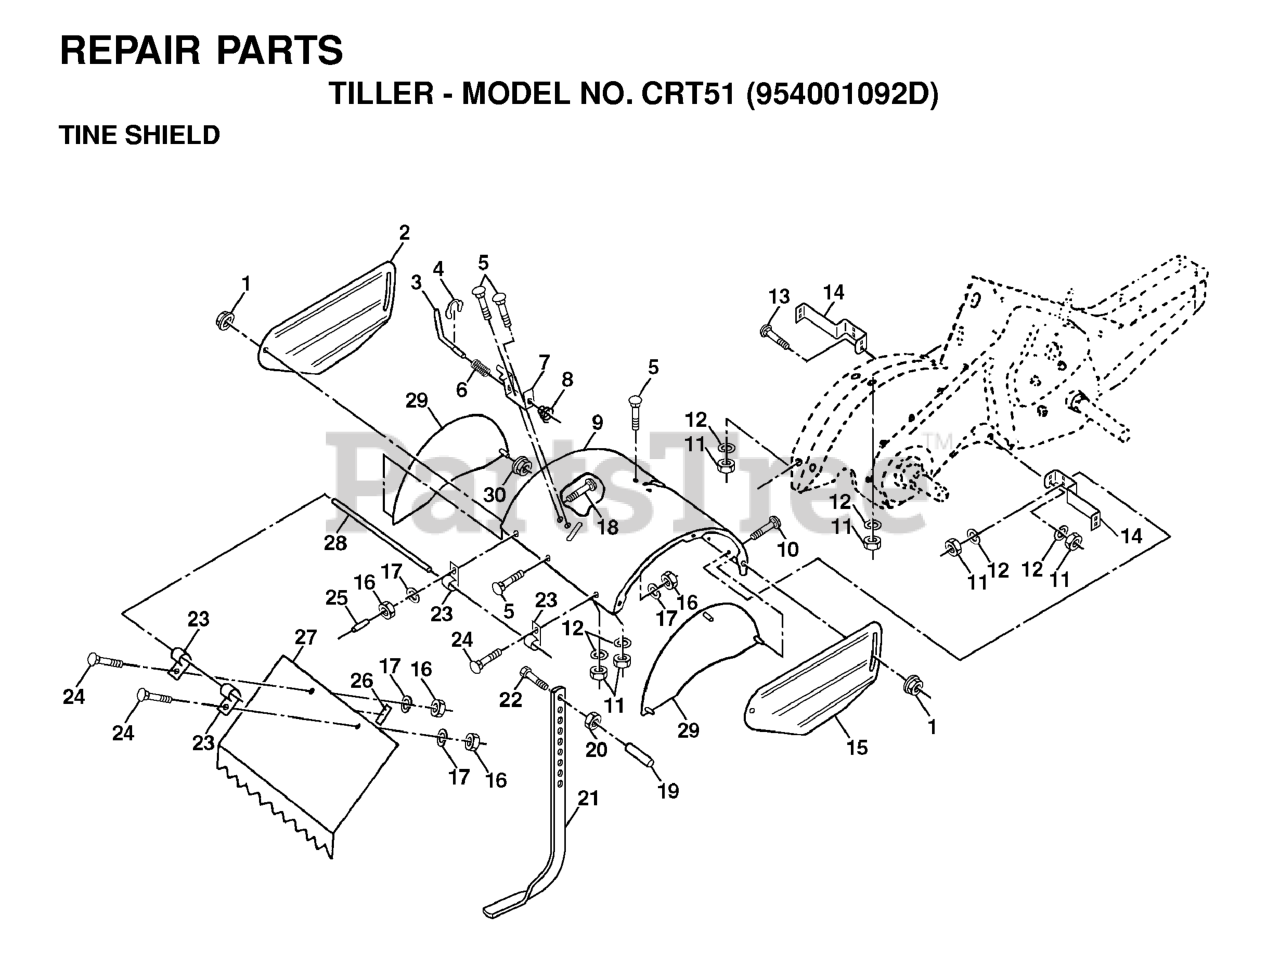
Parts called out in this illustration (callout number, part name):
1	NUT
2	SHIELD SIDE OUTER LH
3	STAKE PIN TI
4	KLIP RING TI
5	RP BOLT 5/16-18 X3/4 ZN/YEL GR
7	BRACKET.LATCH.STAKE.3.20.BLACK
8	SPRING CRT
9	SHIELD
12	WASHER.LOCK.HVY.HLCL.SPR.5/16
13	BOLT.CARRIAGE.5/16-18
14	BRACKET.TINE.SHIELD.TILLER.BLA
15	SHIELD SIDE OUTER RH
16	NUT
17	LOCKWASHER
20	NUT.HEX.3/8-16UNC
21	STAKE.DEPTH.16.CRT.BLACK
22	BOLT.375-16
25	VINYL CAP TI
26	PAD IDLER TI
27	SHIELD LEVELING
28	PIN.HINGE.TILLER
29	SIDE SHIELD
30	LOCKNUT-FLANGE 5/16-18
